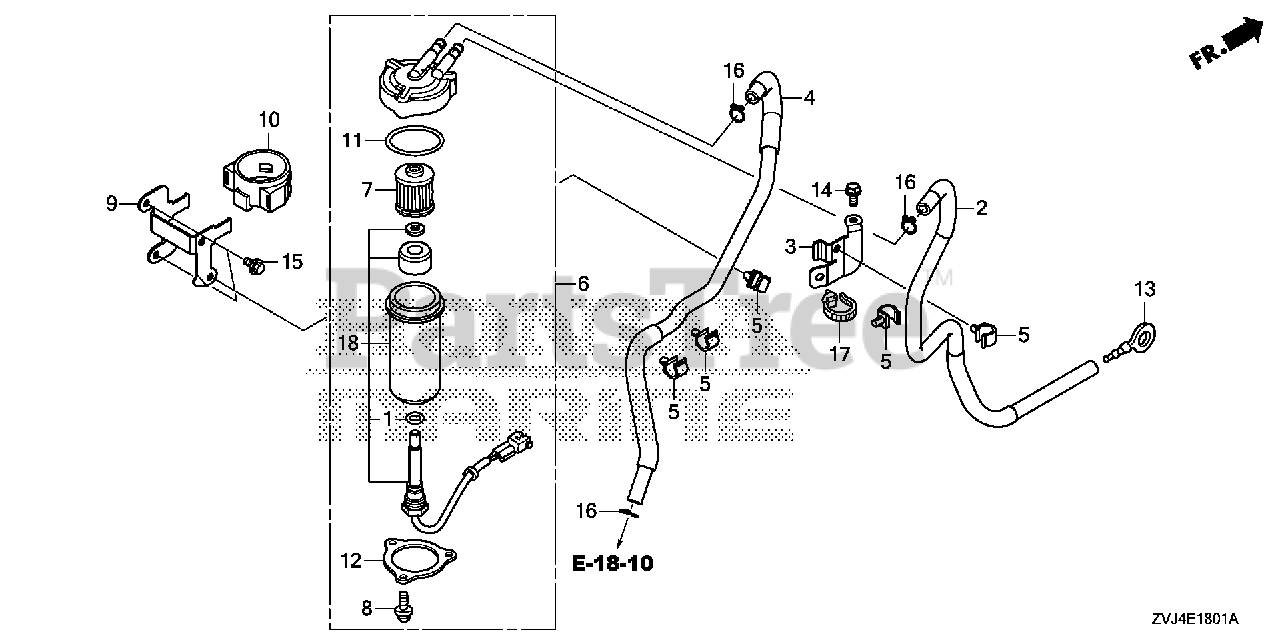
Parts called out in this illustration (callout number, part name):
2	TUBE A, FUEL
3	STAY, FUEL TUBE
4	TUBE B, FUEL
5	CLAMP B, FUEL TUBE
6	FILTER ASSY., FUEL (LOW)
7	FILTER, FUEL
8	SCREW, PAN (5X12)
9	STAY A, FUEL STRAINER
10	SUSPENSION, STRAINER
13	PLUG, FUEL TUBE
14	BOLT, FLANGE (6X14)
15	BOLT, FLANGE (6X10)
16	CLIP, TUBE (B12)
17	CLIP, HARNESS BAND (155.3MM) (BLACK)
18	CUP SET, WATER SEPARATOR
